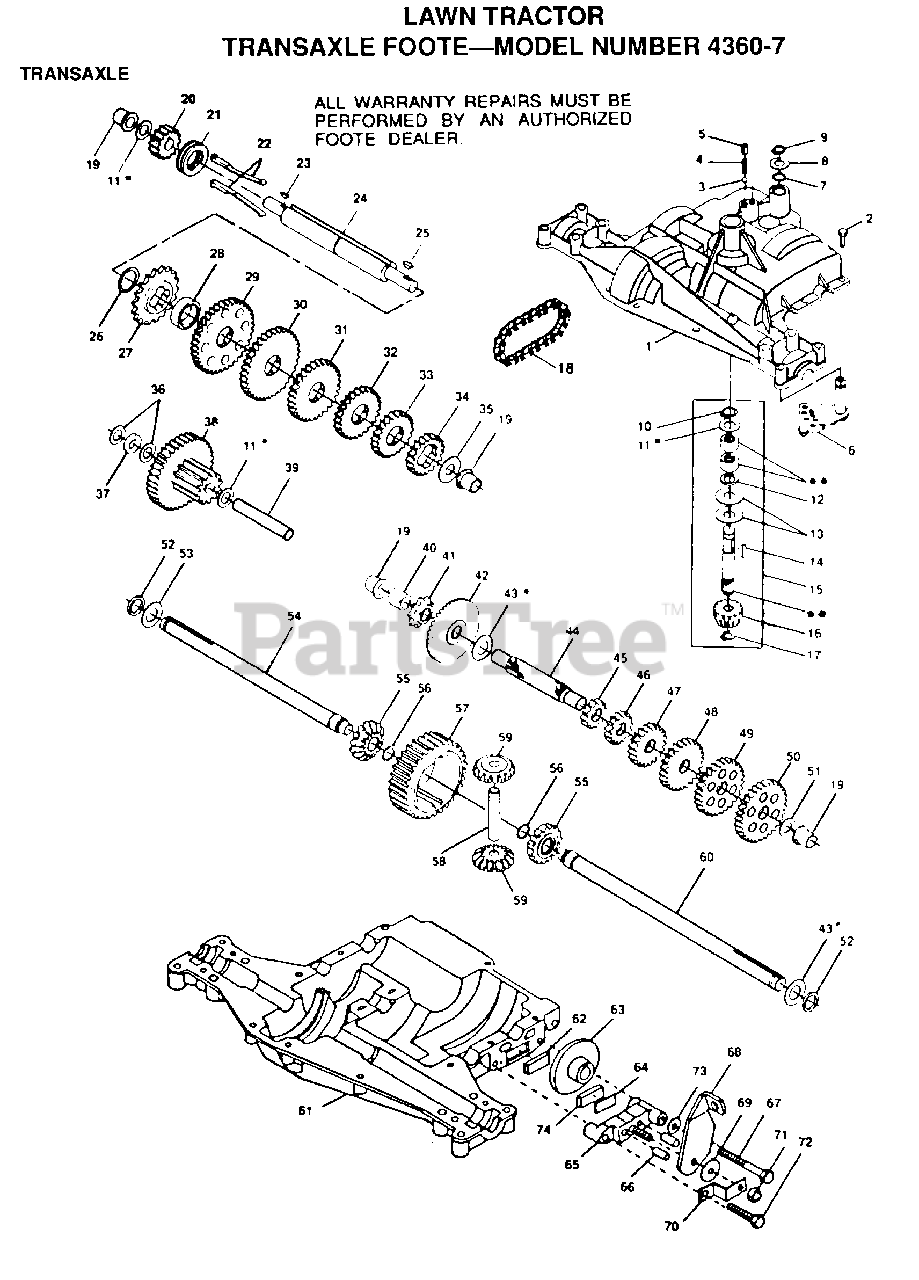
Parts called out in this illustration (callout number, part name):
1	HOUSING UPPER
3	BALL DETENT
4	SPRING, DETENT
5	SCREW, SET
6	ASSY SHIFTER
8	WASHER PLAIN
8A	WASHER PLAIN
8B	WASHER PLAIN
8C	WASHER PLAIN
8D	WASHER PLAIN
8E	WASHER PLAIN
8F	WASHER PLAIN
9	RING RETAINING
10	RING RETAINING
11	WASHER PLAIN
11A	WASHER PLAIN
11B	WASHER, PLAIN .632 X 1.00 X .026
11C	WASHER PLAIN
11D	WASHER PLAIN
11E	WASHER PLAIN
11F	WASHER PLAIN
11G	WASHER PLAIN
11H	WASHER, PLAIN .632 X 1.00 X .060
11I	WASHER PLAIN
13	WASHER, PLAIN .632 X 1.38 X .046
14	KEY WOODRUFF #9
15	ASSY KIT INPUT SHAFT
16	PINION, BEVEL, 14 TEETH
17	RING, RETAINING
18	CHAIN, 24 PITCHES
19	BEARING, FLANGE
20	GEAR SPUR, 14 TEETH
21	COLLAR CLUTCH
22	KEY CLUTCH
23	KEY WOODRUFF #3
24	SHAFT INTERMEDIATE
25	KEY, WOODRUFF, #61
26	RING, RETAINING
27	SPROCKET, 18 TEETH
29	GEAR, SPUR, 37 TEETH
30	GEAR, SPUR, 35 TEETH
31	GEAR, SPUR, 30 TEETH
32	GEAR, SPUR, 25 TEETH
33	GEAR, SPUR, 22 TEETH
35	WASHER, PLAIN .640 X 1.37 X .061
36	WASHER, PLAIN .632 X 1.00 X .026
37	SPACER .630 X 1.00 X .169
38	ASSY GEAR COMB 12&35 TEETH
39	SHAFT IDLER
40	SPACER .635 X .875 X .755
41	SPROCKET, 9 TEETH
42	GEAR, BEVEL, 42 TEETH
43	WASHER PLAIN
43A	WASHER PLAIN
43B	WASHER PLAIN
43C	WASHER PLAIN
43D	WASHER PLAIN
43E	WASHER PLAIN
43F	WASHER, PLAIN .758 X 1.25 X .031
43G	WASHER PLAIN
43H	WASHER PLAIN
43I	WASHER PLAIN
43J	WASHER PLAIN
43K	WASHER PLAIN
43L	WASHER PLAIN
44	SHAFT, DRIVE
45	GEAR, SPUR, 12 TEETH
46	GEAR SPUR, 15 TEETH
47	GEAR, SPUR, 20 TEETH
48	GEAR, SPUR, 25 TEETH
49	GEAR, SPUR, 28 TEETH
50	GEAR, SPUR, 31 TEETH
51	WASHER, PLAIN .632 X 1.00 X .060
53	WASHER PLAIN
54	AXLE LEFT HAND
55	GEAR, MITER, 15 TEETH
56	RING, RETAINING
57	GEAR, SPUR, 32 TEETH
58	SHAFT, CROSS
59	GEAR, MITER, 15 TEETH
60	AXLE, R.H.
61	HOUSING LOWER
62	PUCK, FRICTION
63	DISC, BRAKE
65	JAW, BRAKE
66	PIN, DOWEL
67	SCREW TAPPING
68	LEVER, ACTUATING
69	WASHER, PLAIN .321 X 1.00 X .055
70	BRACKET, ANTI-ROTATION
71	LOCKNUT 5/16-24
72	SCREW TAPPING
73	WASHER PLAIN
74	PUCK, FRICTION
